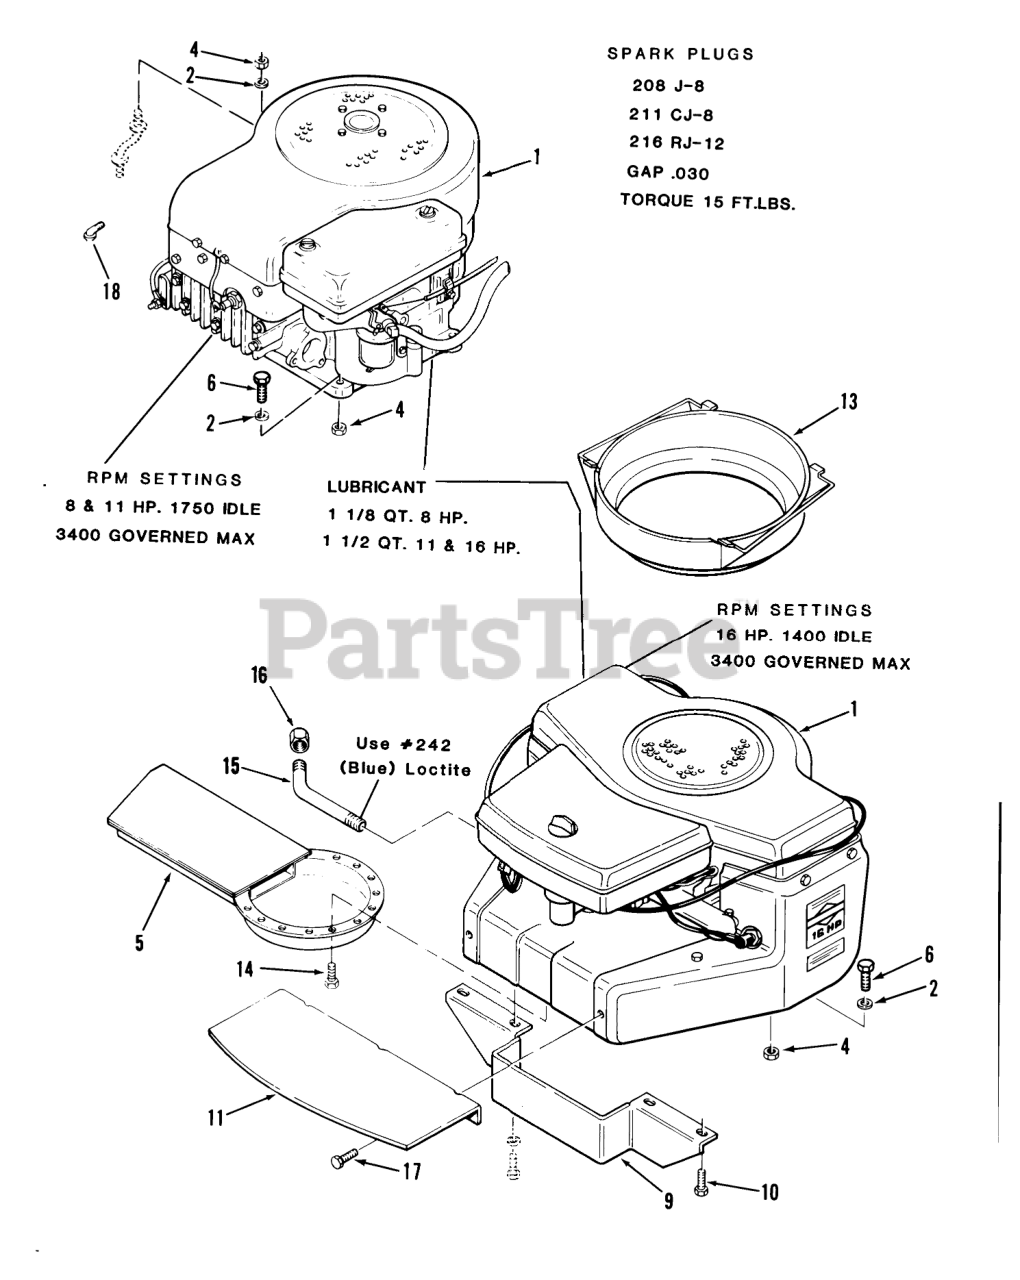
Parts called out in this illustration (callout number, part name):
1	Engine-08HP-B&S Model 191707, Type 2153-01 208-3 Only
2	WASHER 5/16 SAE
4	Nut
5	ASSY EXHAUST DEFLECT
6	Bolt
9	Duct-Rear 216-5 Only
10	Bolt
11	Duct-Front 216-5 Only
13	DUCT-AIR INTAKE
14	SCREW 8-32X3/8
16	Cap
17	Screw-Hex HD Slotted
18	STREET ELBOW 45DEGRE
